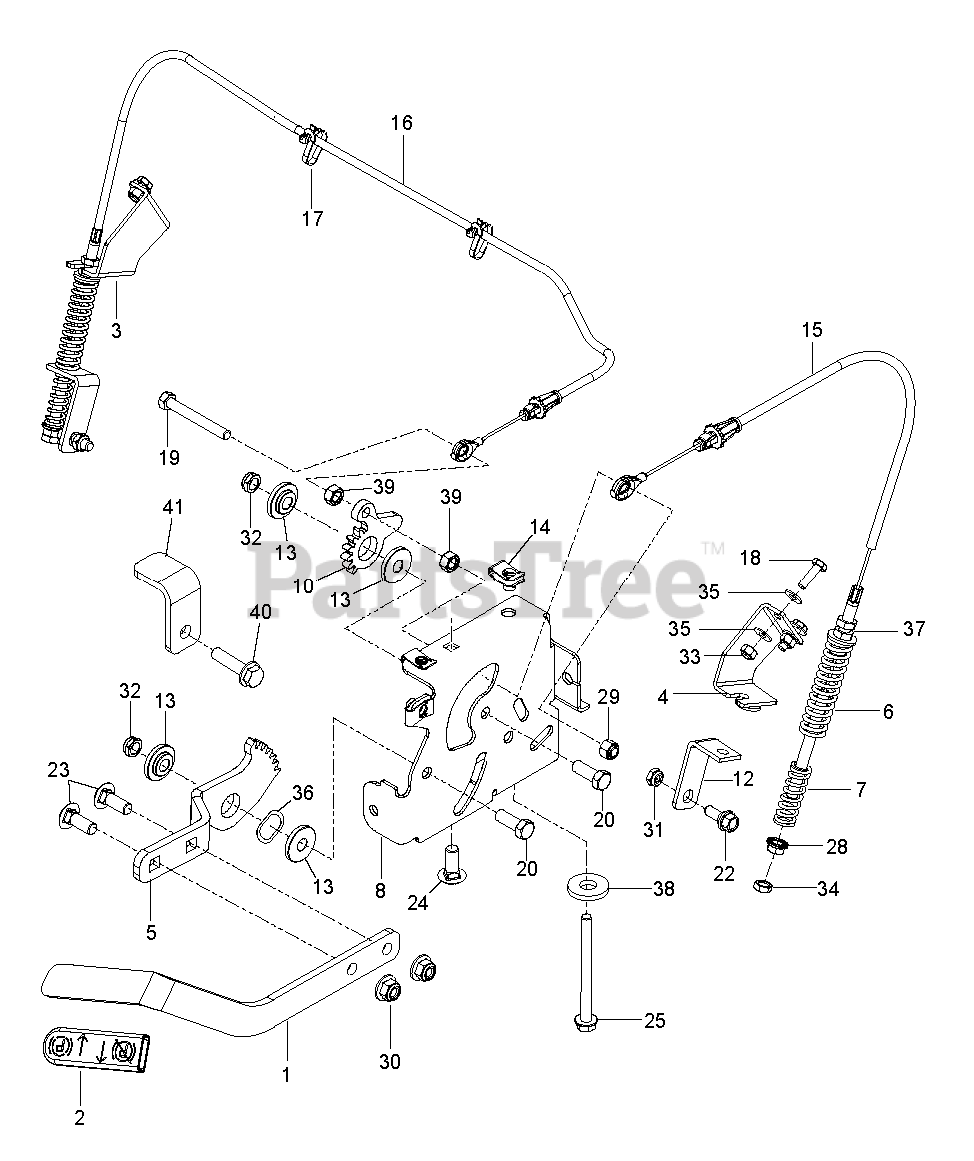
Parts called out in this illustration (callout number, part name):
1	ARM BRAKE BLACK MS-431
2	GRIP, PARK BRAKE
3	BRACKET BRAKE, RT BLACK MS-431
4	BRACKET BRAKE, LT BLACK MS-431
5	GEAR.INPUT.PARKING.BRAKE.MZ
6	SPRING, RETURN
7	SPRING, ENGAGEMENT
8	MOUNT.PNT.BRAKE.MZ.EDIP
10	GEAR OUTPUT;PARKING BRAKE;STAN
12	BRKT, BRAKE, BLK
13	BUSHING, BRAKE
14	U-CLIP 5/16-18 NUT RETAINER
15	CABLE.ASSY.BRAKE.CABLE.SHORT
16	CABLE.ASSY.BRAKE.CABLE.LONG
17	TIE WRAP, 8-3/8", W/CLIP
18	HCS 1/4-20X7/8 GR5
19	HCS 5/16-18 X 2 1/2 TPBLT
20	HCS 3/8-16X1.GRD.5.ZD
22	BOLT, SHOULDER
23	RHSNB 3/8C X 1
24	BOLT 5/16C X 3/4" CARRIAGE
25	HHFS 5/16-18 X 3 3/4
28	NUT 5/16C WHIZ
29	NUT 5/16 NYLOC
30	NUT 3/8-16 HEX FLG NYLOC ZD
31	5/16-18 THIN PROF NY
32	NUT HEX 3/8-16 NYLON, THIN
33	NUT.1/4-20.HEX.NYLOC.ZD
34	NUT 5/16-18 HEX JAM ZD
35	WASHER 1/4 SAE
36	WASHER, .825 X 1.087, WAVE
37	WASHER 3/8 SAE FLAT
38	WASHER.9/16 X 1 3/8 X 12 GA.
39	NUT 5/16C HEX
40	HHFS 5/16-18 X 1.25 TPBLT GD 5
41	BRACKET.PNT.LIMIT.ARM.BRK.EDIP
